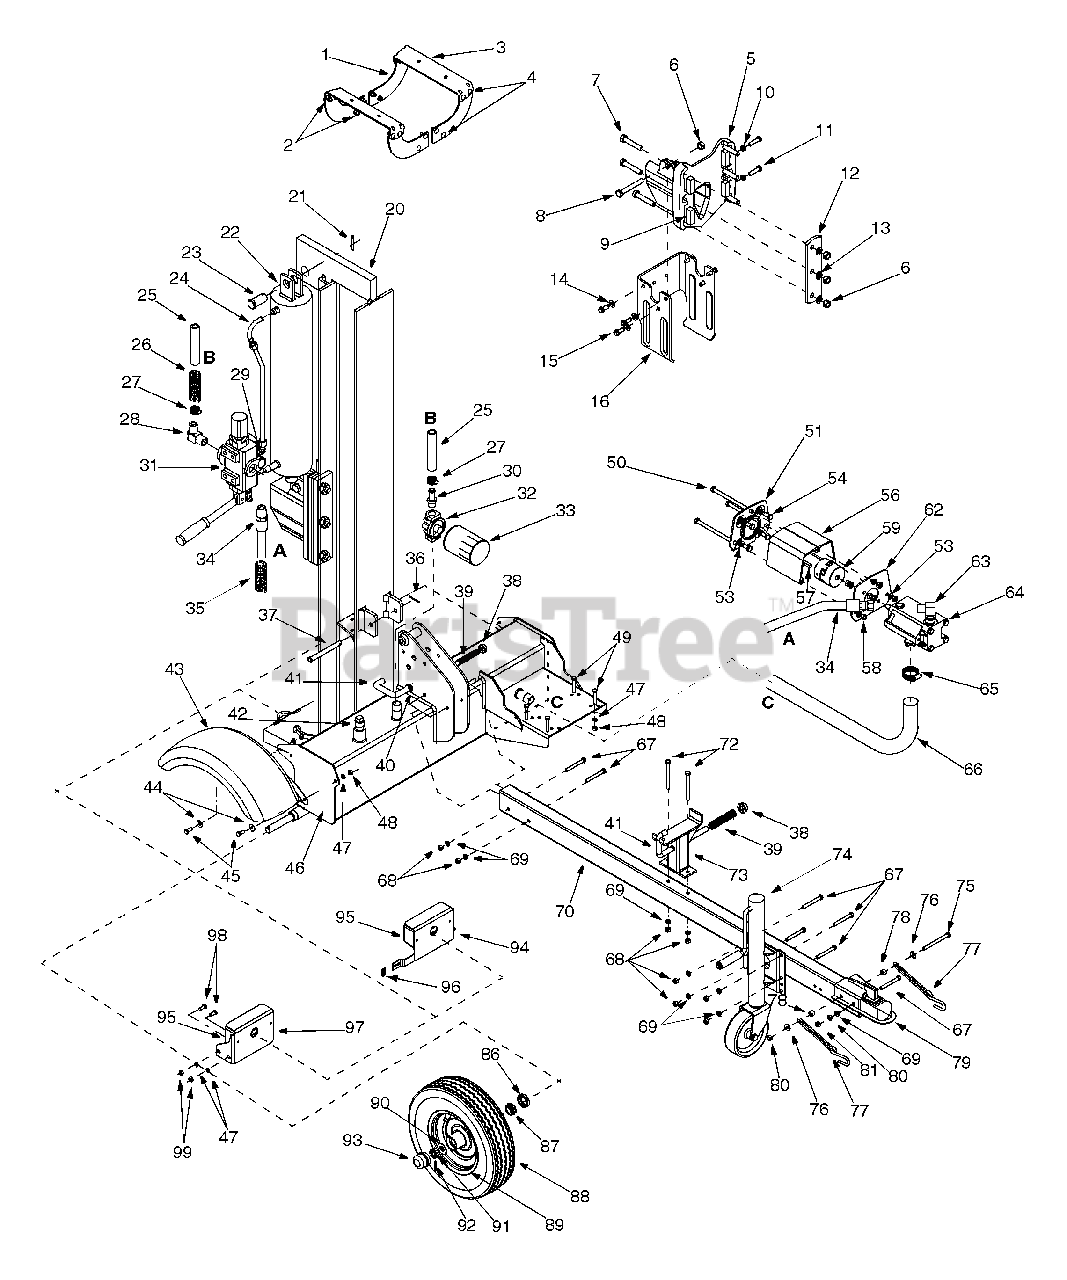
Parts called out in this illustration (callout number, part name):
4	Carriage Bolt 3/8-16 x 1.0
5	Wedge Assembly
6	Lock Nut 1/2-20
7	Hex Cap Screw 1/2-20 x 2.75
8	Hex Cap Screw 1/2-20 x 3.50
9	Adjustable Gib
10	Hex Jam Nut 3/8-24
11	Hex Cap Screw 3/8-24 x 1.5
13	Lock Washer 1/2
14	Flat Washer .406 ID x .875 OD
15	Hex Washer Screw 3/8-16 x 1.
22	Kit Seal 5.0" for Best Metals cylinder 718-0313
22	Hydraulic Cylinder
22	Kit Seal 5.0" for XINGHUI cylinder 718-0313A
22	Kit Seal 5.0" for ENERGY cylinder 718-0313A
23	Clevis Pin
24	Hydraulic Tube
25	Return Hose 3/4" ID x 44" Lg.
26	Hose Guard
27	Hose Clamp 5/8"
28	Return Elbow
29	90 Degree Solid Male Adapter
30	3/4" Hose Adapter
32	Filter Housing
33	Oil Filter
34	High Pressure Hydraulic Hose
35	Hose Guard
36	Cotter Pin 1/8"
37	Hinge Pin 1/2 x 4.8" Lg.
39	Compression Spring 4"
40	Flat Washer .635 ID x .93 OD
41	Locking Rod
42	Vented Dipstick
45	Hex Cap Screw 5/16-24 x .75
46	Frame Assembly 7.0 Gal
47	Lock Washer 5/16
48	Hex Nut 5/16-24
49	Hex Cap Screw 5/16-24 x 1.75
50	Hex Cap Screw 5/16-24 x 5.25
53	Lock Washer 5/16
54	Hex Cap Screw 5/16-24 x .625
56	Shoulder Spacer
57	Key, 1/4 x 2.00
57	Key, 3/16 x .75
58	Hex Screw 5/16
59	Flexible Coupling, 1.00 x .4375
63	Adapter 7/8-14
64	Gear Pump, Hyd (16 GPM)
64	Pump Kit
64	Gear Pump, Hyd (15 GPM)
65	Hose Clamp
66	Suction Hose
67	Hex Cap Screw 3/8-16 x 3.0
68	Hex Nut 3/8-16
69	Lock Washer 3/8
72	Hex Cap Screw 3/8-16 x 4.0
75	Hex Cap Screw 3/8-16 x 4.25
76	Flat Washer .385 ID x .870 OD
77	Chain
79	Hitch Coupler
80	Lock Nut 3/8-16
81	Hex Jam Nut 3/8-16
86	Bearing Seal
87	Bearing Cone
88	Wheel Assembly
89	Rim Assembly
90	Flat Washer .76" ID x 1.5" OD
91	Slotted Nut 3/4-16
92	Cotter Pin 5/32" x 1-1/4" Lg.
96	Nut 1/4-20
99	Hex Nut 5/16-24
